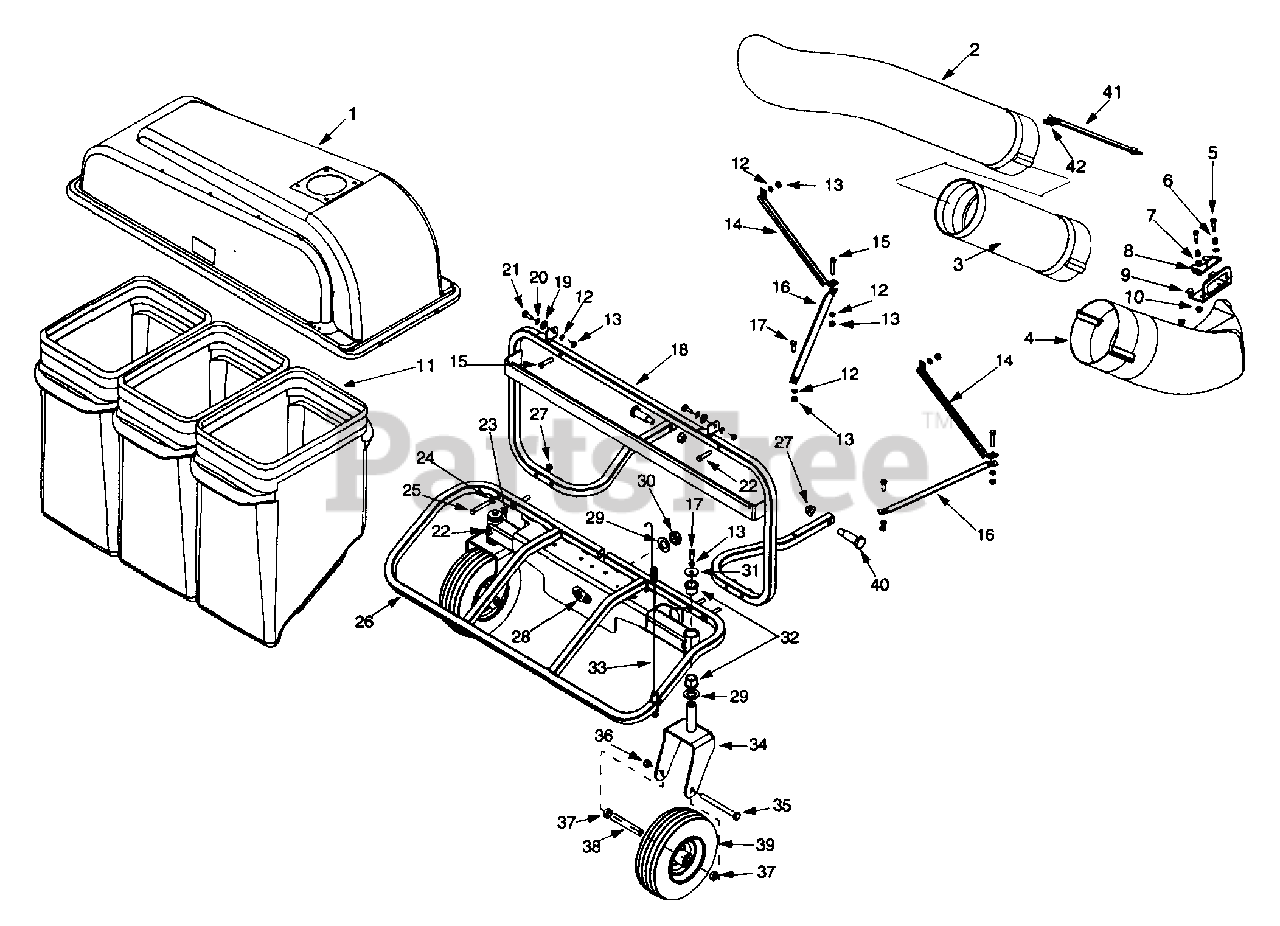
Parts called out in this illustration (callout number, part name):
1	Cover Assembly
2	Upper Tube Chute
3	Chute Extension
4	Discharge Chute
5	Shoulder Screw
6	Compression Spring .50 OD x .5
7	Flat Washer
8	Bagger Latch
9	Chute Bracket
10	Lock Nut 5/16-18
11	Grass Bag Container
12	Lock Washer 3/8
13	Hex Nut 3/8-16
15	Hex Cap Screw 3/8-16 x 1.75
17	Hex Cap Screw 3/8-16 x 1.0
20	Flat Washer.510 ID x .750 OD
21	Shoulder Screw
22	Grease Fitting
25	Hex Cap Screw 3/8-16 x 2.5
28	Pivot Pin Assembly
30	Lock Nut
31	Flat Washer .390 ID x 1.5 OD
32	Flange Bearing
35	Hex Cap Screw 1/2-20 x 5.50
36	Hex Lock Nut 1/2-20
37	Spacer .790 ID x .347 Lg.
38	Wheel Spacer
39	Wheel Assembly
40	Shoulder Bolt
41	Retainer Strap Assembly
42	Retainer Clip
